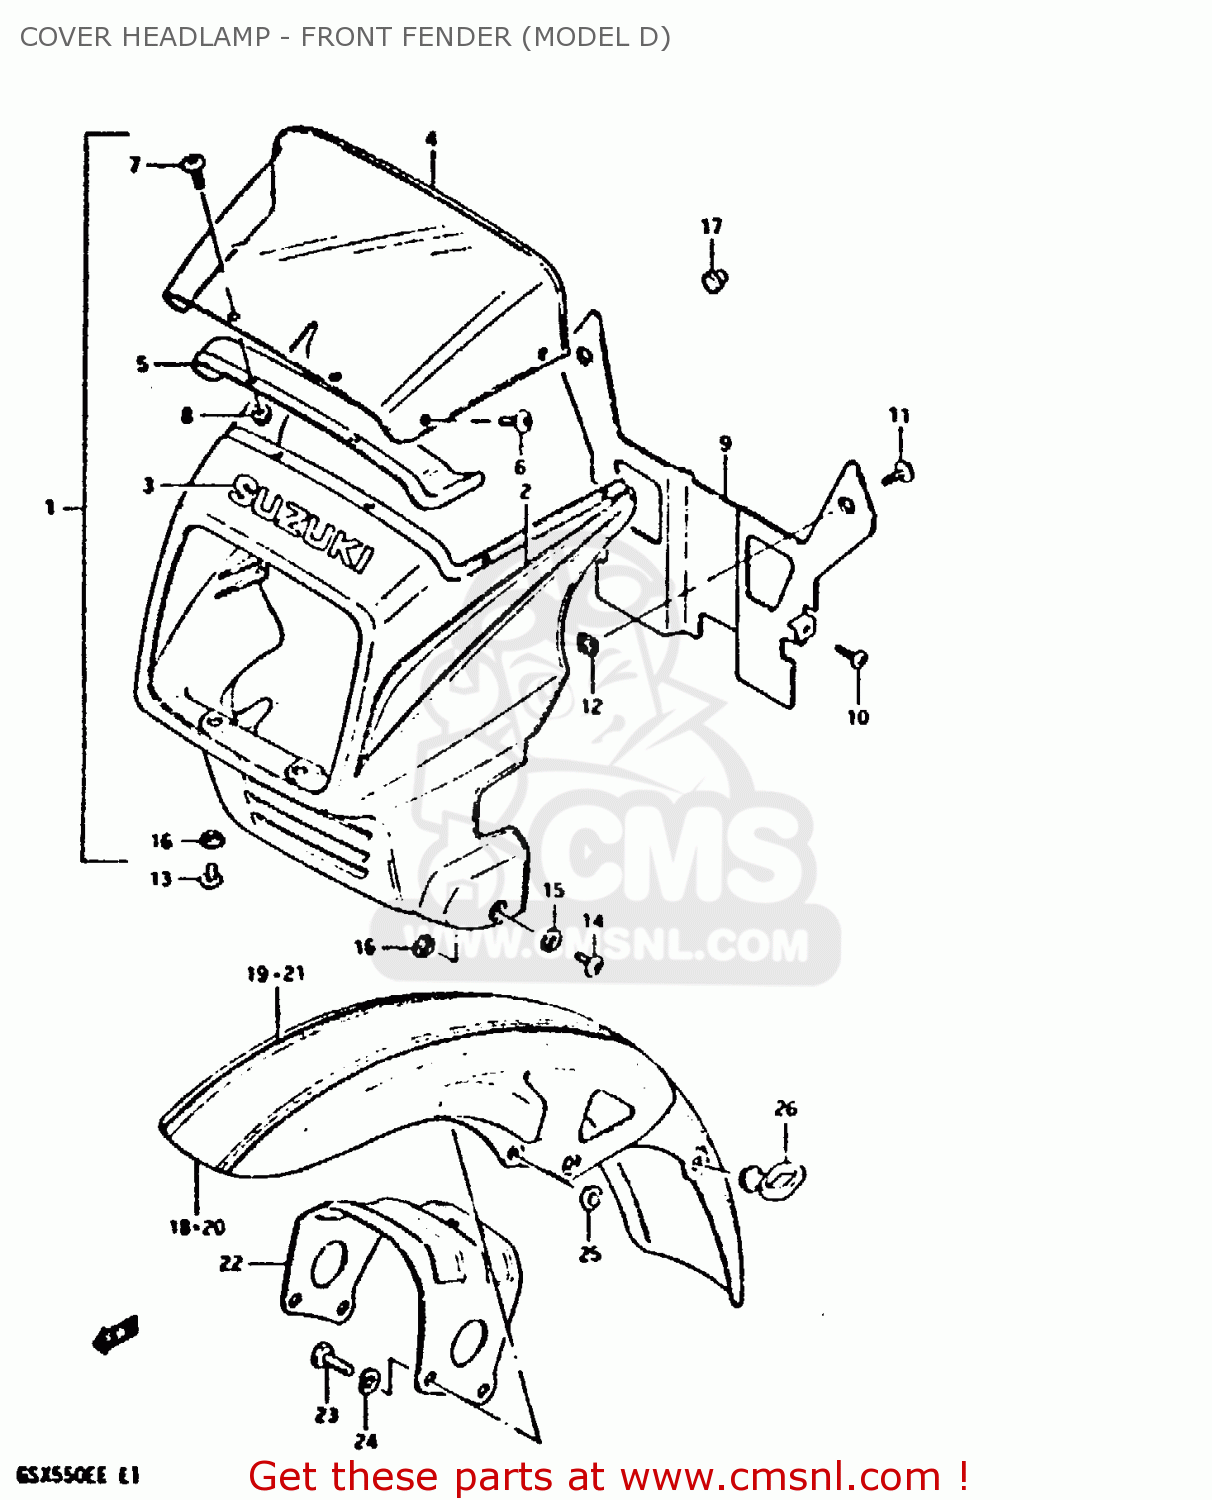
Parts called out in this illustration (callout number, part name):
1	HOUSING,HEADLAMP (COWLING)
2	TAPE SET,HEADLAMP
3	EMBLEM,HEADLAMP
4	WINDOW,COVER HEADLAMP
5	COVER,HEADLAMP,UPPER
6	SCREW(5X12)
7	SCREW
8	NUT
9	PLATE,HEADLAMP COVER
10	SCREW
11	SCREW
12	NUT
13	SCREW 6X12
14	SCREW 6X12
15	WASHER (6.5X18X1.6)
16	WASHER
17	PLUG
18	FENDER,FRONT
19	TAPE SET,FRONT FENDER
20	FENDER,FRONT
21	TAPE,FRONT FENDER
22	BRACE,FRONT FENDER
23	BOLT
24	LOCK WASHER
25	WASHER
26	GUIDE,CABLE
